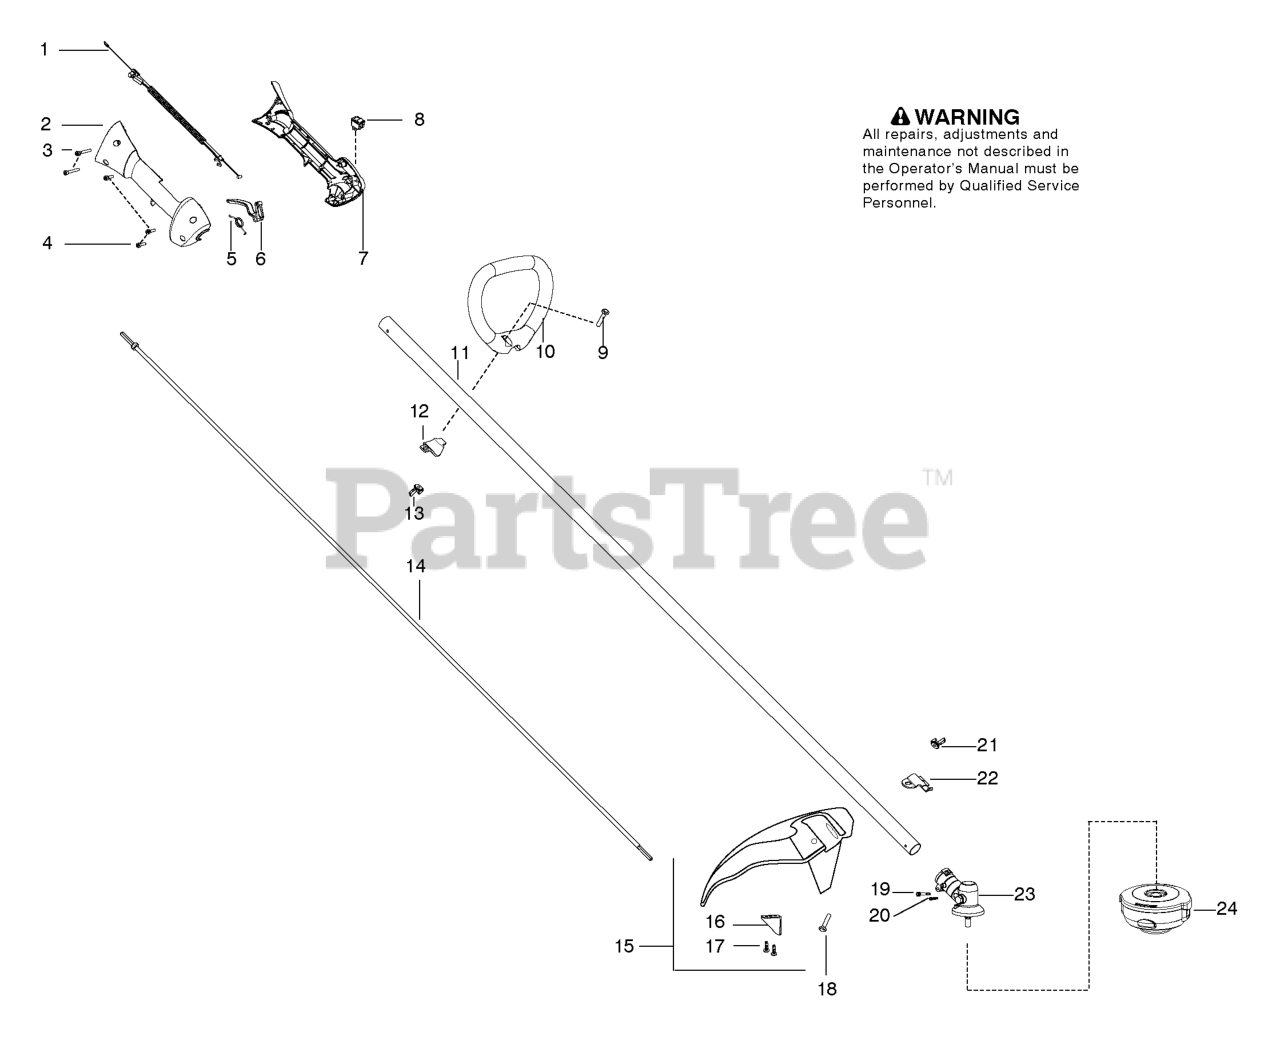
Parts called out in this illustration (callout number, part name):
1	%ASSY CABLE WIRE HARNESS
2	HOUSING-THROTTLE (RH)
4	SCREW M4 X 1.75 PT 16MM
5	SPRING TRIGGER
6	TRIGGER THROTTLE
7	HSG THROTTLE LH
8	KIT SWITCH
9	BOLT, TYPE 2
10	HANDLE ASSIST
11	KIT DRIVESHAFT SST
12	CLAMP ASSIST HANDLE
13	WINGNUT, TYPE 2
14	FLEXSHAFT 57
15	KIT-SHIELD
16	LINE LIMITER 17"
18	BOLT, TYPE 2
19	SCREW - CARB. ADAPTOR
20	SCREW 8-16 X 9/16 (PLAS
21	WINGNUT, TYPE 2
22	BRACKET SHIELD STRAIGHT SHAFT
24	TRIMMER HEAD T25
